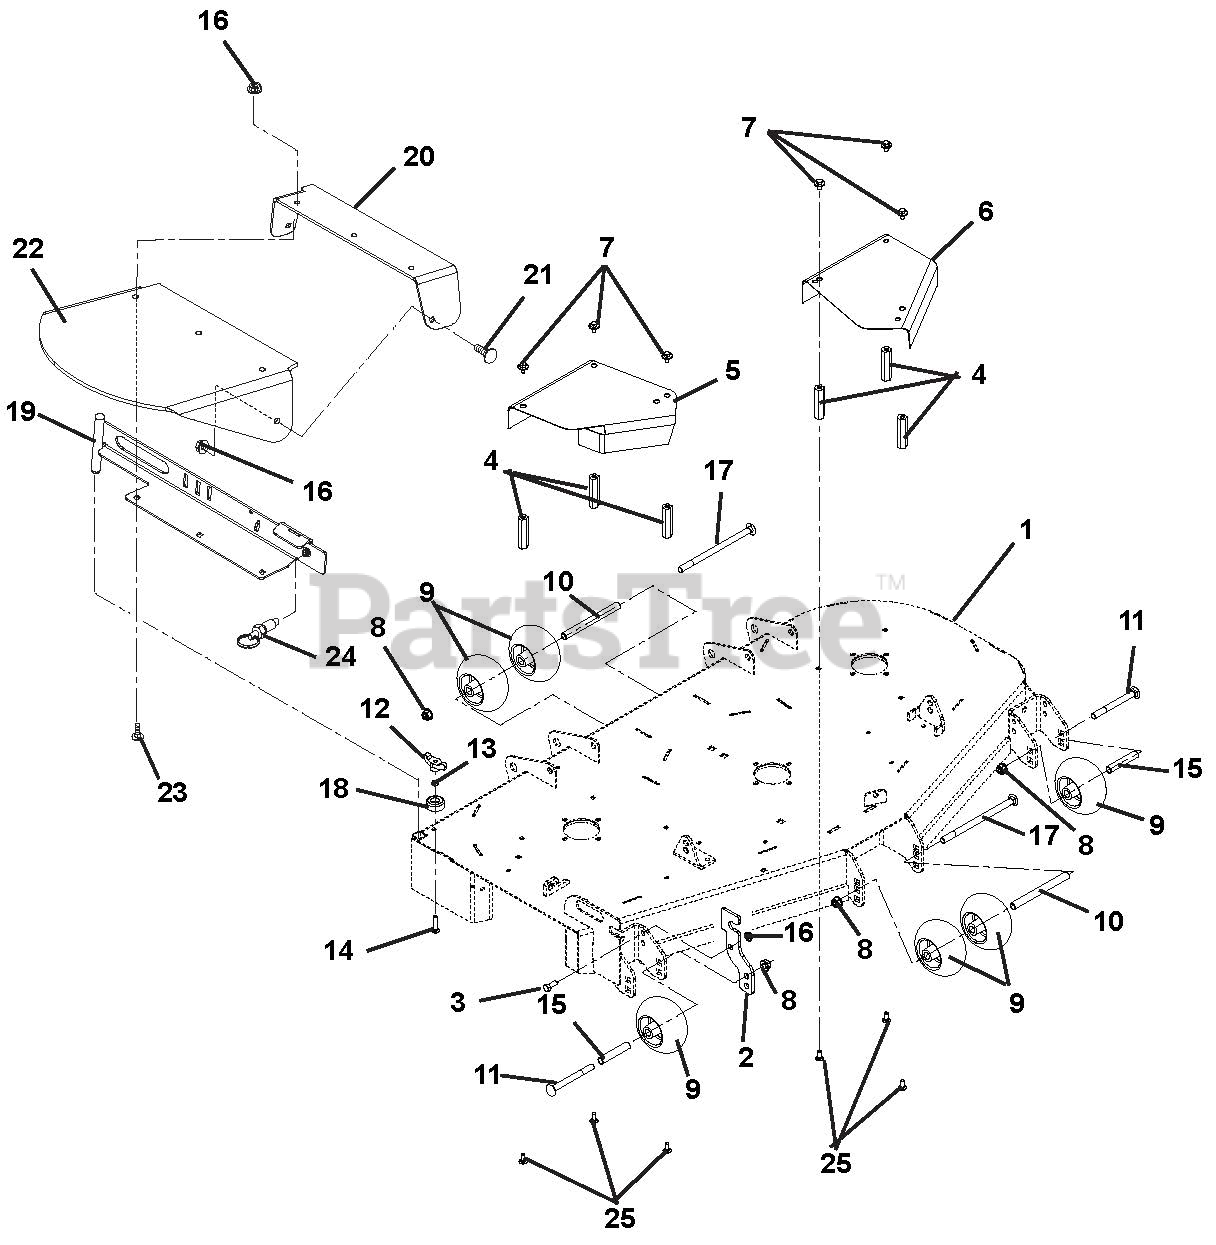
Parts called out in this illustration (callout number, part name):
1	Weldment, 52" Side Discharge Deck
1	Weldment, 60" Side Discharge Deck
2	Bracket, Chute Storage
3	Bolt, Hex .38-16 x 1.00 Grade 5
4	Nut, Coupling .31-18 x 3.00
5	Guard, 48"-52" Right Hand Spindle Sheave Guard
5	Guard, 60" Right Hand Spindle Sheave
6	Guard, 44"-52" Left Hand Spindle Sheave
6	60" DECK Left Hand Sheave Guard- Red
7	Bolt, SEMS .31-18 x .62
8	Nut .50-13 Nyloc Flange
9	Anti-Scalp Wheel
11	Bolt, Round Head Square Neck .50-13 x 5.00
12	Knob, Wing .312-18 UNC
13	Nut, Locking-Center .31-18
14	Bolt, Round Head Square Neck .31-18 x 1.50 Grade 5
15	Spacer, .510 x .625 x 3.35
16	Nut, .38-16 Nyloc Flange
17	Bolt, Round Head Square Neck .50-13 x 8.50
18	Bumper, Recessed 1.50 x .63 , .31 Thru Hole
19	52 in. & 60 in. Discharge Chute Mounting Weldment
20	Rubber Discharge Chute Support
21	Bolt, Round Head Square Neck .38-16 x 1.00 Grade 5
22	Chute, Rubber Discharge
23	Bolt, Round Head Square Neck .38-16 x 1.25 Grade 5
24	Pin, Pull
25	Bolt, Round Head Square Neck .31-18 x .75 Loctite
